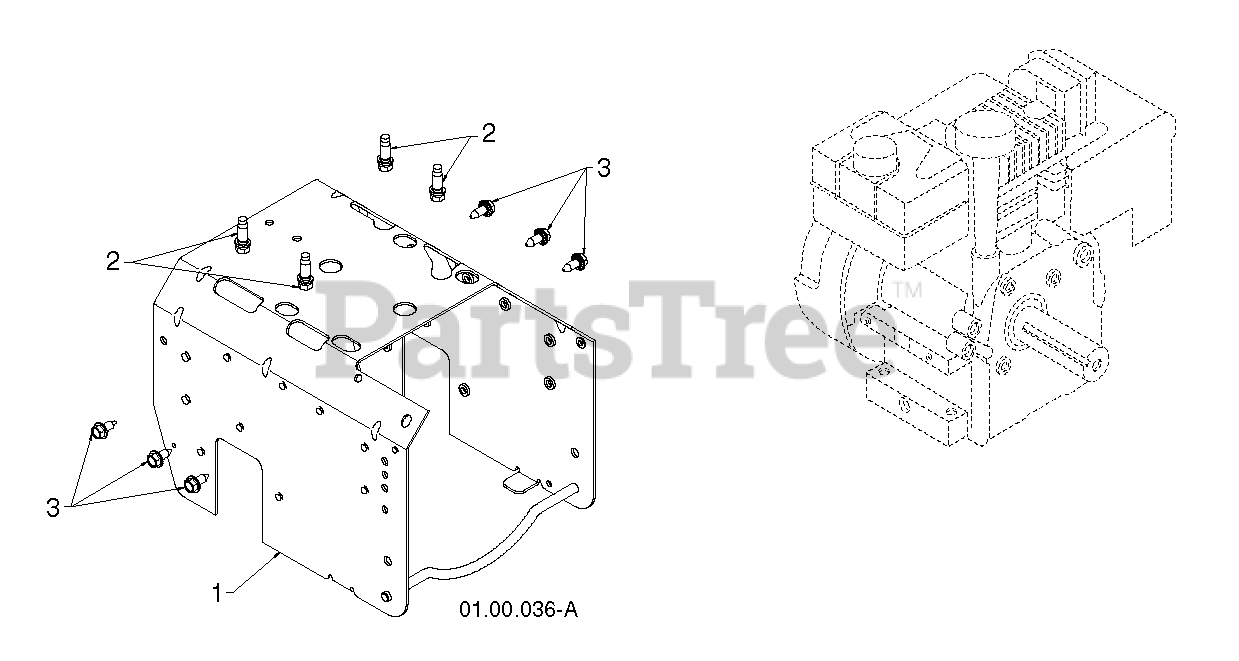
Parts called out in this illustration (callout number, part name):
1	FRAME.WELD.HYDRO.668.PNT
2	BOLT 3/8-16X1-1/8
3	BOLT.HEX.HD.WASHER.5/16-18X.75
